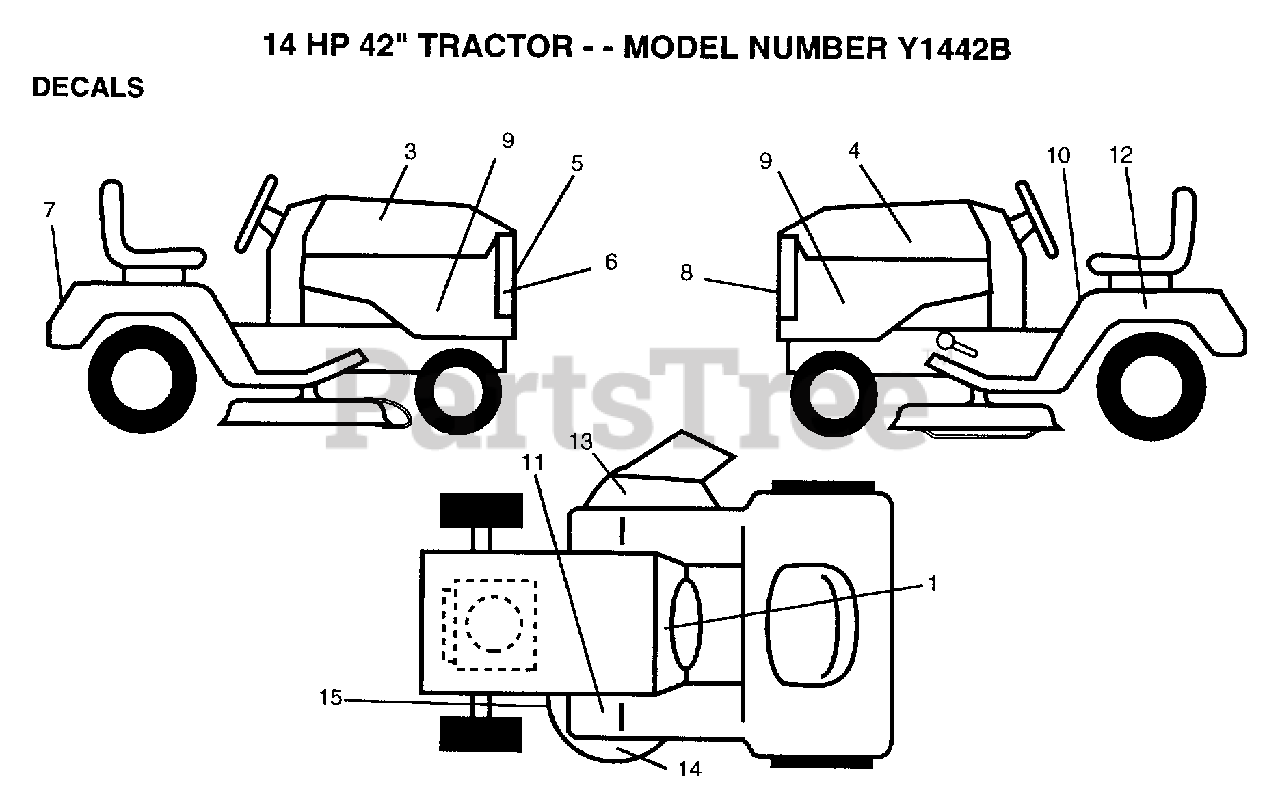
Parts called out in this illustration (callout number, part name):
1	DECAL.DASH.INSTR.
5	DECAL.GRILL.YARDP
9	DECAL.PANEL.SIDE
10	DECAL CAUTION
11	DECAL T
12	DECAL
13	"DECAL, WARNING"
15	DECAL
